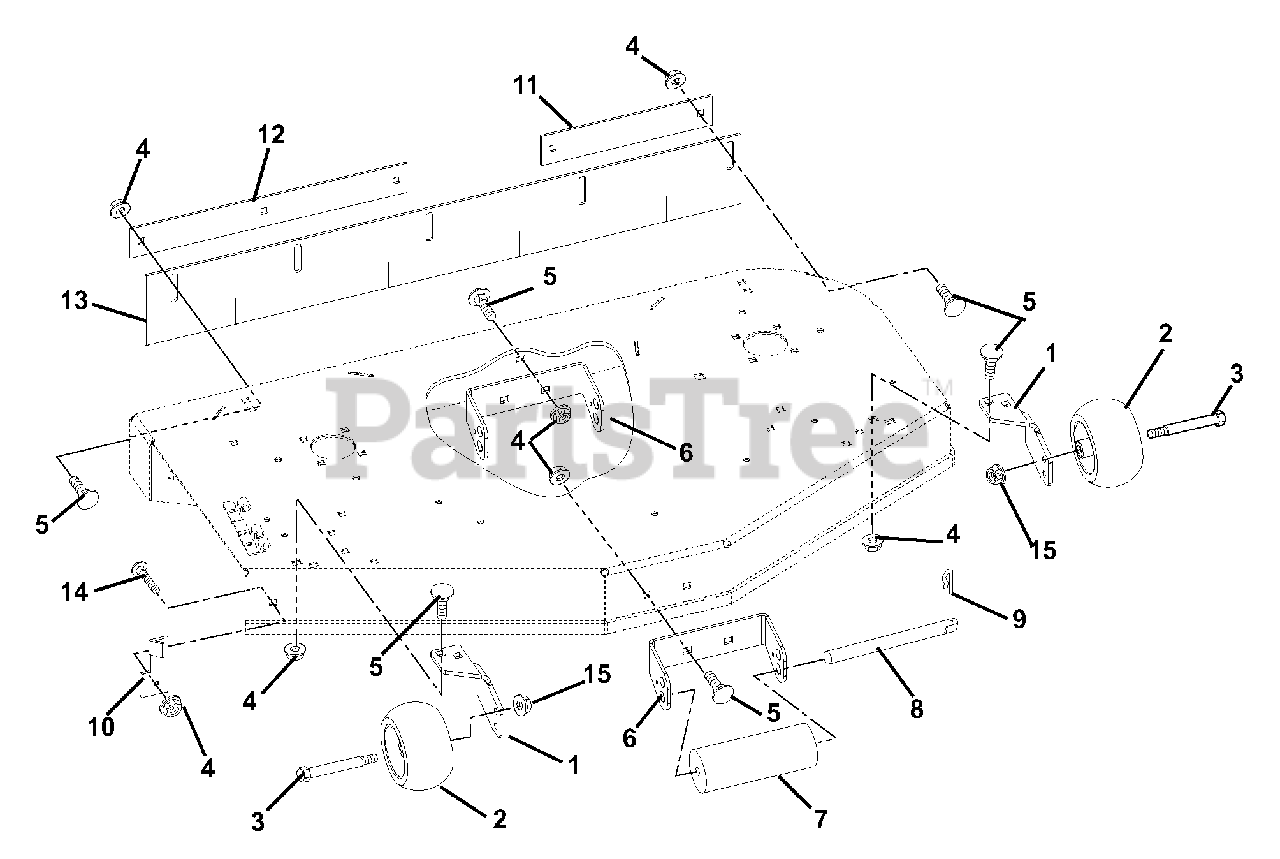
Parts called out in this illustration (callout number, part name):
1	BRACKET, ANTI SCALP
2	WHEEL 5 X 3
3	BLT-SHLDR .38-16X2.50 HWH G5
4	@NUT-LK-NYL-FLG .38-16 YWZC
5	@BLT-RDHDSQNK .38-16X1.00 G5YZ
6	BRACKET, ROLLER MOUNT
8	PIN, ROLLER
9	PIN, SPRING CLIP
10	BRACKET, CHUTE LOCK
11	BAR, LH RETAINER STRIPER
12	BAR, RETAINING STRIPER-40"
12	BAR, RETAINING STRIPER-44"
12	BAR, RETAINING STRIPER-52"
13	STRIPER, RUBBER-40"
13	STRIPER, RUBBER-44"
13	STRIPER, RUBBER-48"
13	STRIPER, RUBBER-52"
14	@BLT-RDHDSQNK .38-16X1.50 G5YZ
15	@NUT-LK-TOP-FLG .38-16 YWZC
